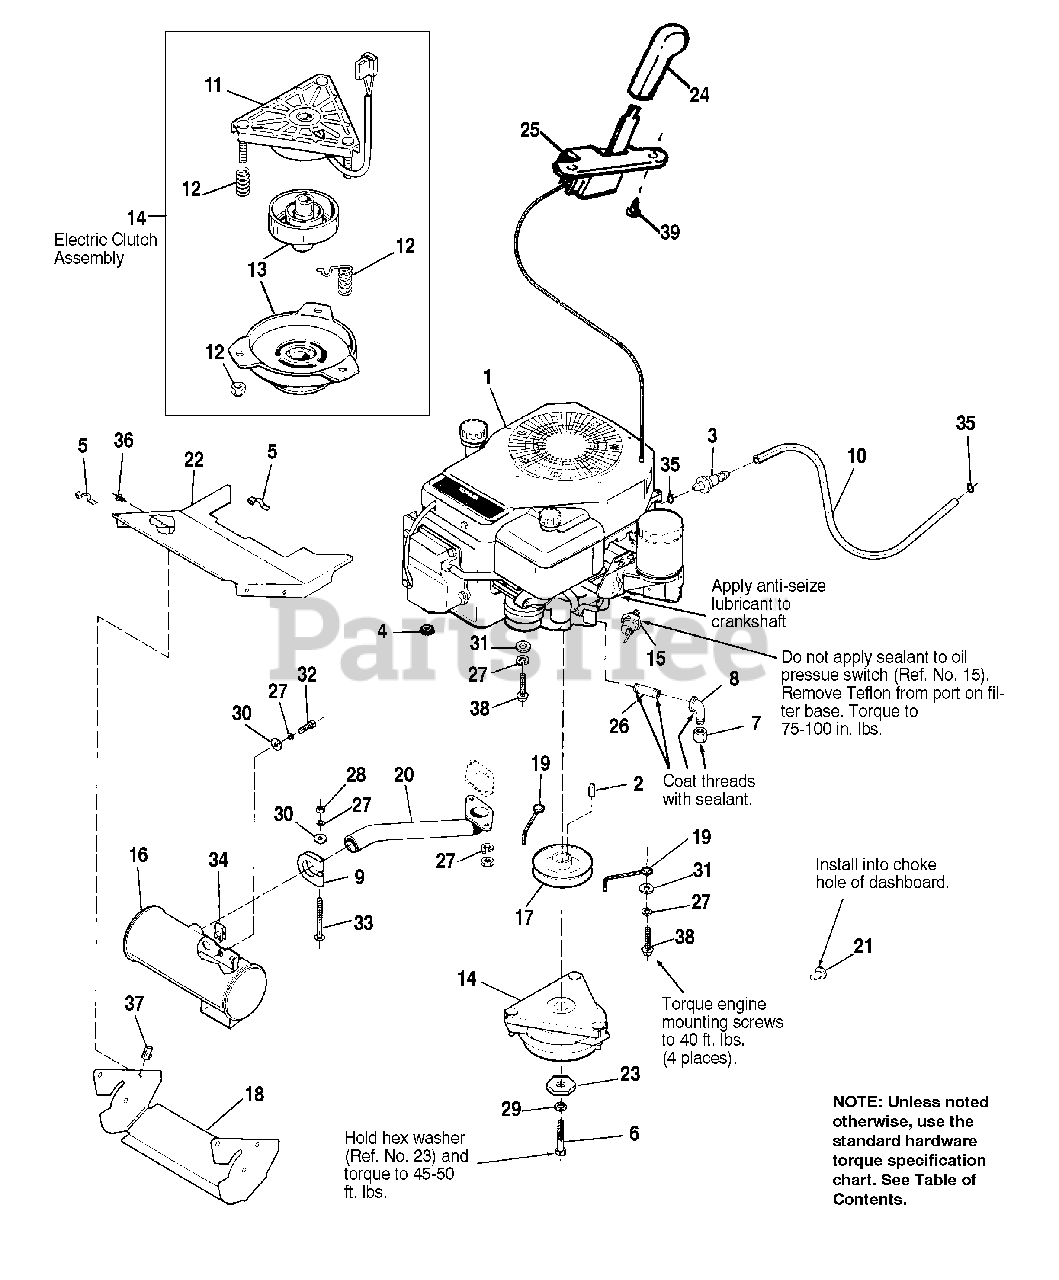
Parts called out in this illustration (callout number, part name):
1	ENGINE, Kohler (Model No. - Type No.)
2	KEY, Hi-Pro
3	FUEL FILTER
4	LOCKWASHER, External Tooth, 5/16
5	CLIP
6	CAPSCREW, M10-1-1/2 x 60mm
8	STREET ELBOW, 3/8 Pipe
9	CLAMP, Muffler
10	HOSE, Fuel, 45-1/2" Long
11	FIELD ASSY., Clutch
12	SPRING & NUT KIT
13	ROTOR & ARMATURE ASSY.
14	ELECTRIC CLUTCH
15	SWITCH, Oil Pressure
16	MUFFLER ASSY.
17	PULLEY ASSY.
18	DUCT, Lower Muffler
20	PIPE, Exhaust
21	FASTENER, Panel
22	DUCT, Top, Muffler
23	WASHER, Hex
24	KNOB, Throttle
25	THROTTLE CONTROL ASSY.
26	PIPE NIPPLE, 3/8 x 2
27	LOCKWASHER, 5/16
28	NUT, Full, Hex, 5/16-18
29	LOCKWASHER, 7/16
30	WASHER, Plain, 5/16
31	WASHER, Plain, 5/16
32	CAPSCREW, Hex, 5/16-18 x 1
33	CARRIAGE BOLT, 5/16-18 x 2-3/4
34	PAL NUT, 5/16-18
35	CLAMP, Hose
36	SCREW, Flange, Whizlock, 1/4-20 x 5/8
37	PAL NUT, 1/4-20
38	SCREW, Taptite, M8-1-1/4 x 30 mm
39	SCREW, Hex, Washer Hd., Plastite, 1/4-20 x 1/2
